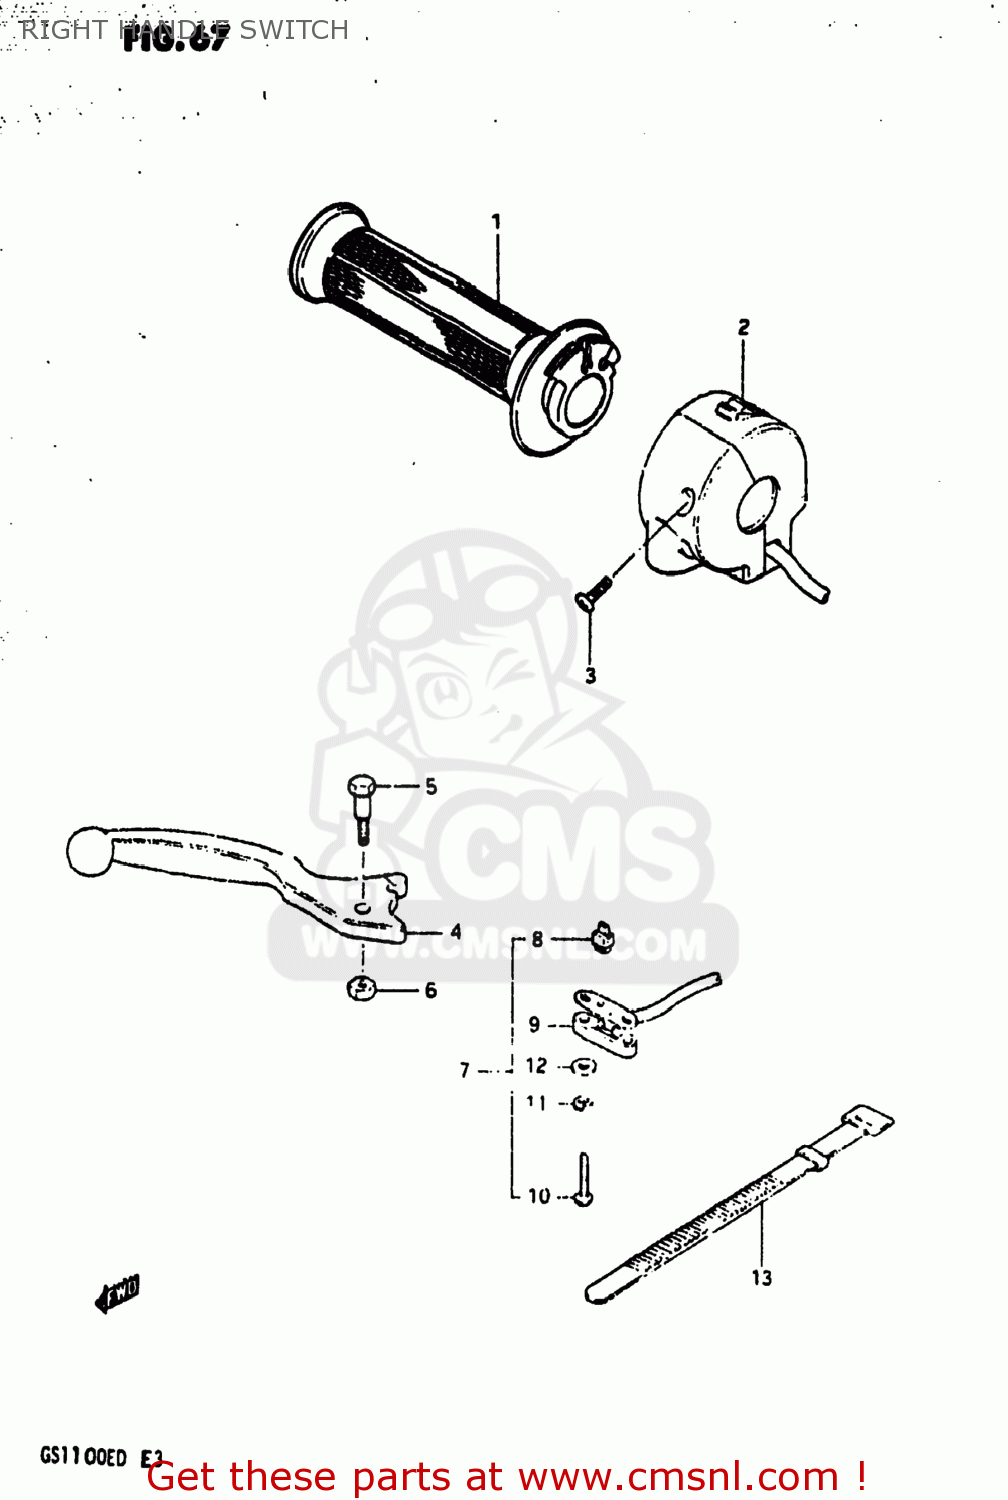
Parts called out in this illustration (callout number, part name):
1	GRIP,THROTTLE
2	SWITCH ASSEMBLY,HANDLE,RIGHT
3	SCREW
4	LEVER,BRAKE
5	BOLT
6	NUT 6MM
7	SWITCH ASSEMBLY
8	CONTACT,SWITCH
9	COVER,FR BK TERMINAL BASE
10	SCREW
11	LOCK WASHER
12	WASHER
13	CLAMP(L:120)
14	BUTTON,STARTER
15	SPRING,STARTER BUTTON
16	CONTACT,STARTER BUTTON
